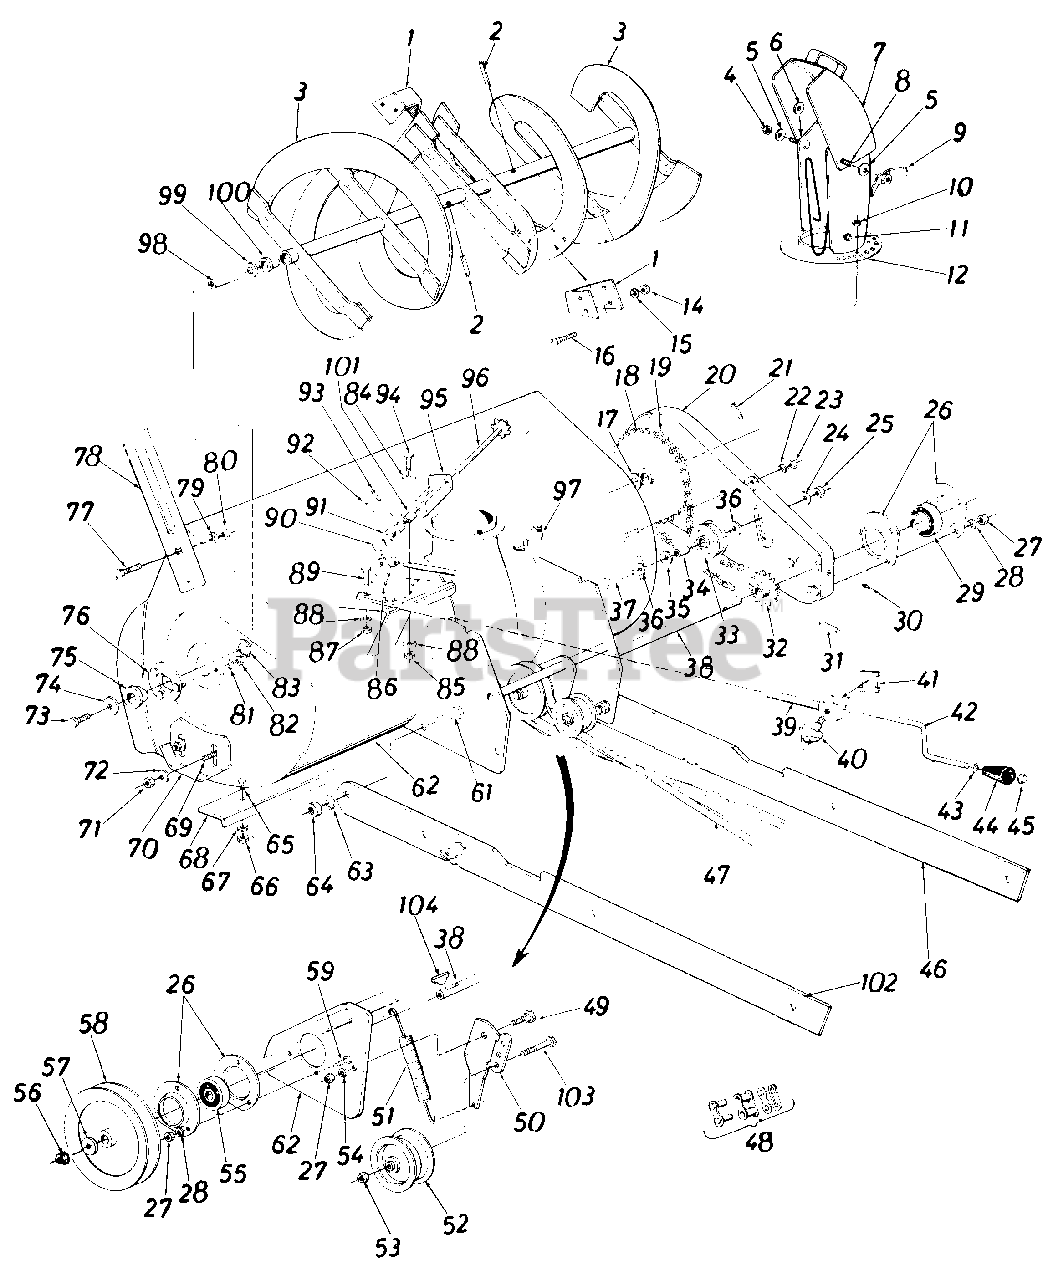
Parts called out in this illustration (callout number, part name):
1	Spiral Plate
2	Spring Pin Spir. 5/16 x 1 .75" Lg.
3	Spiral Ass'y.
4	Hex Cent. L-Nut 5/16-18 Thd.
5	Bell. Wash.
6	Fl-Wash.
7	Top Chute Ass'y.
8	Car. Bolt 5/16-18 x .62" Lg.
9	Chute Wing Ass'y.
10	Hex Cent. LNut 1/4-20 Thd.
11	Push Cap .188" Dia. Rod
12	Chute Ass'y.
14	Hex Nut 5/16-18 Thd.*
15	L-Wash. 5/16" Scr.*
16	Car. Bolt 5/16-18 x .62" Lg.*
17	Fl-Wash.
18	Sprocket Hub Ass'y. 40 Teeth
19	#420 Chain x 1/2" Pitch 77 Links
20	Chain Guard Ass'y.
21	Spring Pin Spir. 5/16
22	L-Wash. 5/16" Scr.*
23	Hex Nut 5/16-18 Thd.*
24	Bell. Wash.
25	Hex Ins. L-Nut 3/8-16 Thd.
26	Bearing Housing
27	Hex Nut 5/16-18 Thd.*
28	L-Wash. 5/16" Scr.*
29	Self Aligning Brg. w/Set Scr.
31	Spring Pin Spir. 5/16 x 1.75
32	14 Teeth Sprocket Ass'y.
33	1.875" Dia. Flat Idler
34	Idler Spacer
35	Fl-Wash.
36	Fl-Wash.
37	Hex Scr. 3/8-16 x 2.00" Lg.*
38	Drive Shaft
39	Crank Support Tubing Ass'y.
40	Hand Knob 5/16-18 Thd.
41	Chute Crank Brk't.
42	Chute Crank
43	Fl-Wash.
44	Knob-Black 3/8" Dia. Hole
45	Push Nut 3/8" Rod
46	Linkage Arm Ass'y.
47	"V"-Belt 1/2" x 85" Lg. (Kevlar)
48	Master Link for #420 Chain
49	Shoulder Scr.
50	Idler Brk't. Ass'y.
51	Extension Spring
52	Fl. Idler with Flange
53	Hex Ins. Jam Nut 3/8-16 Thd.
54	L-Wash. 5/16" Scr.*
55	Self Aligning Brg.
56	Hex Nut 3/4-10 Thd.
57	Fl-Wash.
58	5.50 O.D. x 5/8 Pulley
59	Hex Sems Scr. 5/16-18 x .75"
61	Hex Scr. 1/2-13 x 1.25" Lg.*
62	Spiral Housing Ass'y.
63	L-Wash. 1/2" Scr.*
64	Hex Nut 1/2-13 Thd.*
65	Car. Bolt 5/16-18 x .62" Lg.*
66	Hex Nut 5/16-18 Thd.*
67	L-Wash. 5/16" Scr.*
69	Car. Bolt 3/8-16 x .75" Lg.*
70	Slide Shoe
71	Hex Nut 3/8-16
72	Bell. Wash.
73	Hex Scr. 5/16-18 x .62" Lg.
74	Fl-Wash.
75	Flange Brg. with Flats
76	Brg. Housing Ass'y.
77	Car. Bolt 5/16-18 x .62" Lg.
78	Guide Blade
79	L-Wash. 5/16" Scr.*
80	Hex Nut 5/16-18 Thd.*
81	L-Wash. 5/16" Scr.*
82	Hex Nut 5/16-18 Thd.*
83	Snap Ring for 1.50" Dia. Shaft
84	Bell. Wash.
85	Hex Nut 5/16-18 Thd.*
86	Cotter Pin 3/32 x 1.00" Lg.*
87	Hex Nut 5/16-18 Thd.*
88	L-Wash. 5/16" Scr.*
89	Hex Scr. 5/16-18 x 1.50" Lg.
90	Joint Block
91	Joint Brk't. Ass'y.
92	Spring Pin Roll 3/16" x .81" Lg.*
93	Spring Pin Roll 1/8 x .75" Lg.*
94	Hex Scr. 5/16-18 x .75" Lg.*
95	Chute Brk't.
96	Sprocket Shaft Ass'y.
97	Chute Flange Keeper Ass'y.
98	Spiral Axle
99	Fl-Wash.
100	Plastic Bushing
101	Spacer .380 I.D. x .630 O.D. x .565
102	Linkage Arm Ass'y. R.H.
103	Hex Bolt 3/8-16 x 1.75" Lg.*
104	#61 Hi-Pro Key
